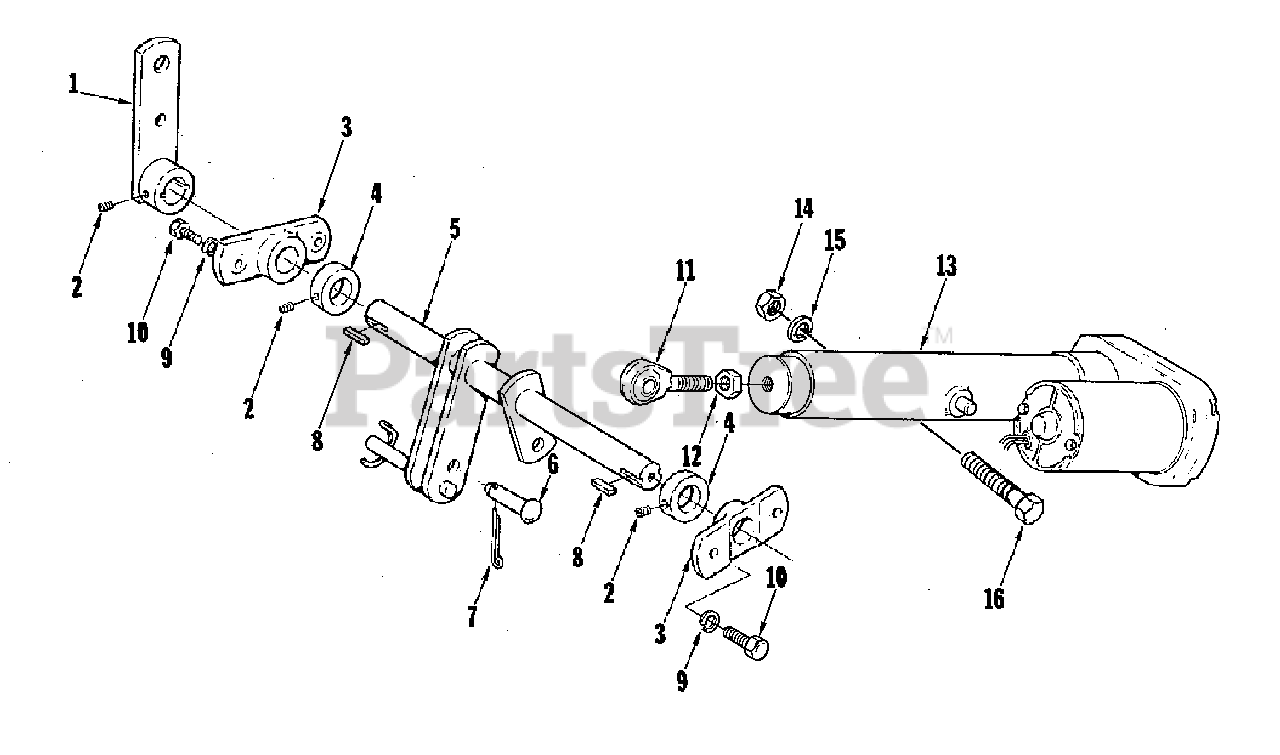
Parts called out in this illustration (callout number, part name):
1	LEVER ASSEMBLY, Front Lift
2	SCREW, Set, 5/16-18 x 5/16
3	BEARING, Lift Lever
5	SHAFT ASSEMBLY, Lift
8	KEY, Parallel
9	WASHER, Lock, 3/8
10	SCREW, Hex Head Cap, 3/8-16 x 3/4
12	NUT, Jam, Hex, 1/2-20
13	ACTUATOR, Electric
14	NUT, Hex, 5/16-18
15	WASHER, Lock, 5/16
16	SCREW, Hex Cap, 5/16-18 x 3-1/2
